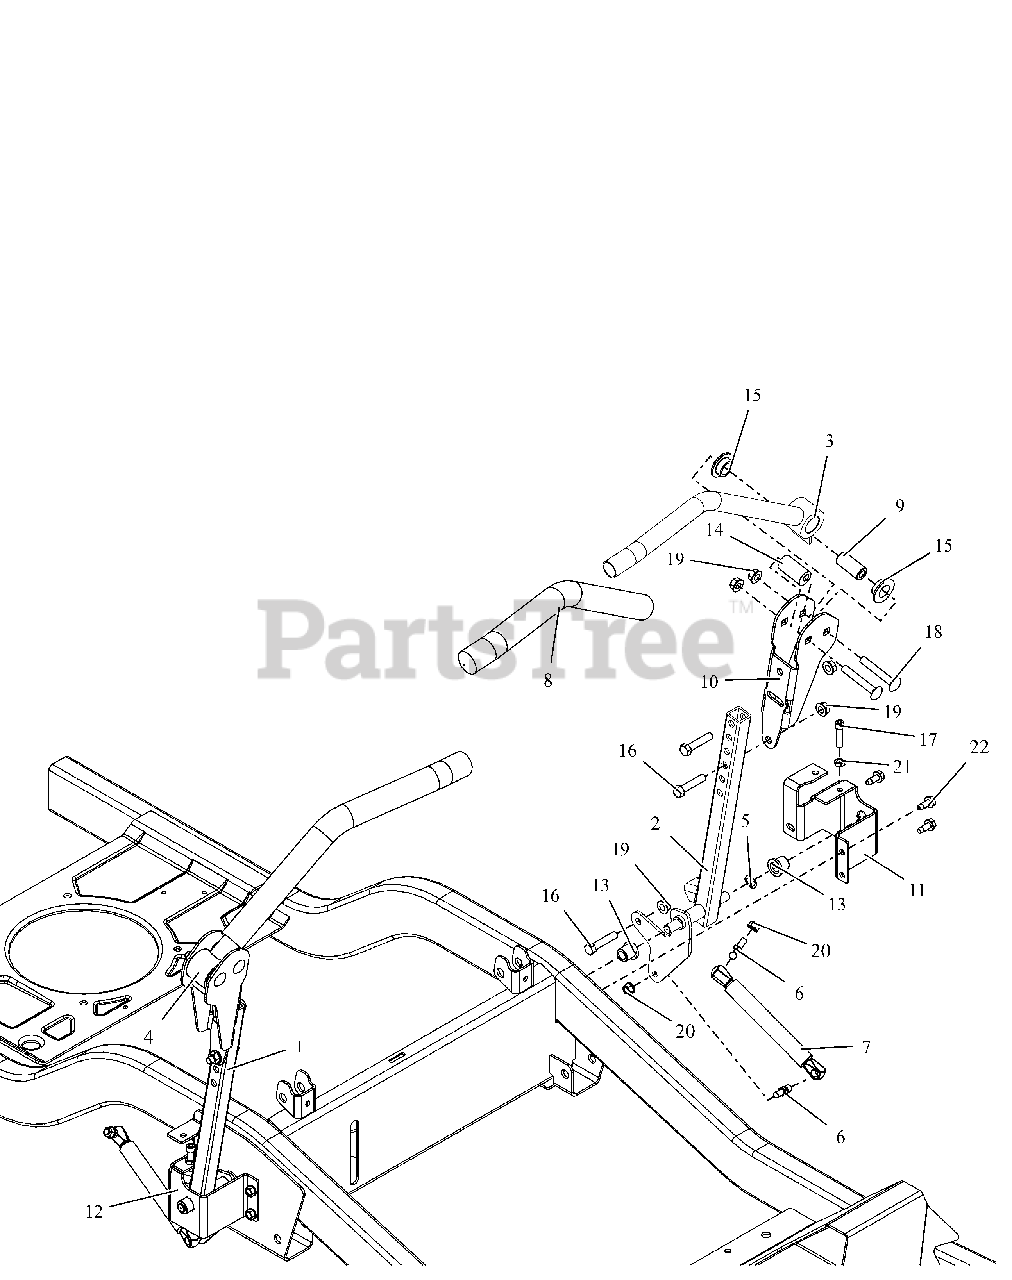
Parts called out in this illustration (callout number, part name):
1	WLDMT, STEERING RH
2	WLDMT, STEERING LH
3	WLDMT, CONTROL HANDLE- BLK
4	WLDMT, CONTROL HANDLE- BLK
5	WAVE WASHER .531X.781X.125FH
6	STUD- BALL
7	DAMPER
8	GRIP, HANDLEBAR
9	SPACER, STEERING ARM
10	ADJ UPPER CONTROL ARM BRKT-BLK
11	BRKT, STEERING ARM MOUNT -LH
12	BRKT, STEERING ARM MOUNT -RH
13	BHSG-FLG .500X.750X.750X.125
14	BSHG, ECCENTRIC.406X.875X1.625
15	BSHG-FLG .762X1.48X.44 NYL
16	BLT, HEX .38-16X1.75 G5 ZCC
17	SCR, SKH .312-18X1.25 GR8 ZC120
18	BLT, RHSSN.38-16X2.50 G5 ZCC
19	NUT-LK-TOP-FLG .38-16 ZC120
20	NUT,LK-CTR-FLG .31-18 GF ZCC
21	NUT-JAM .312-18 G2 ZCC
22	SCR,TAP .312-18X.75 HWH TR ZCC
